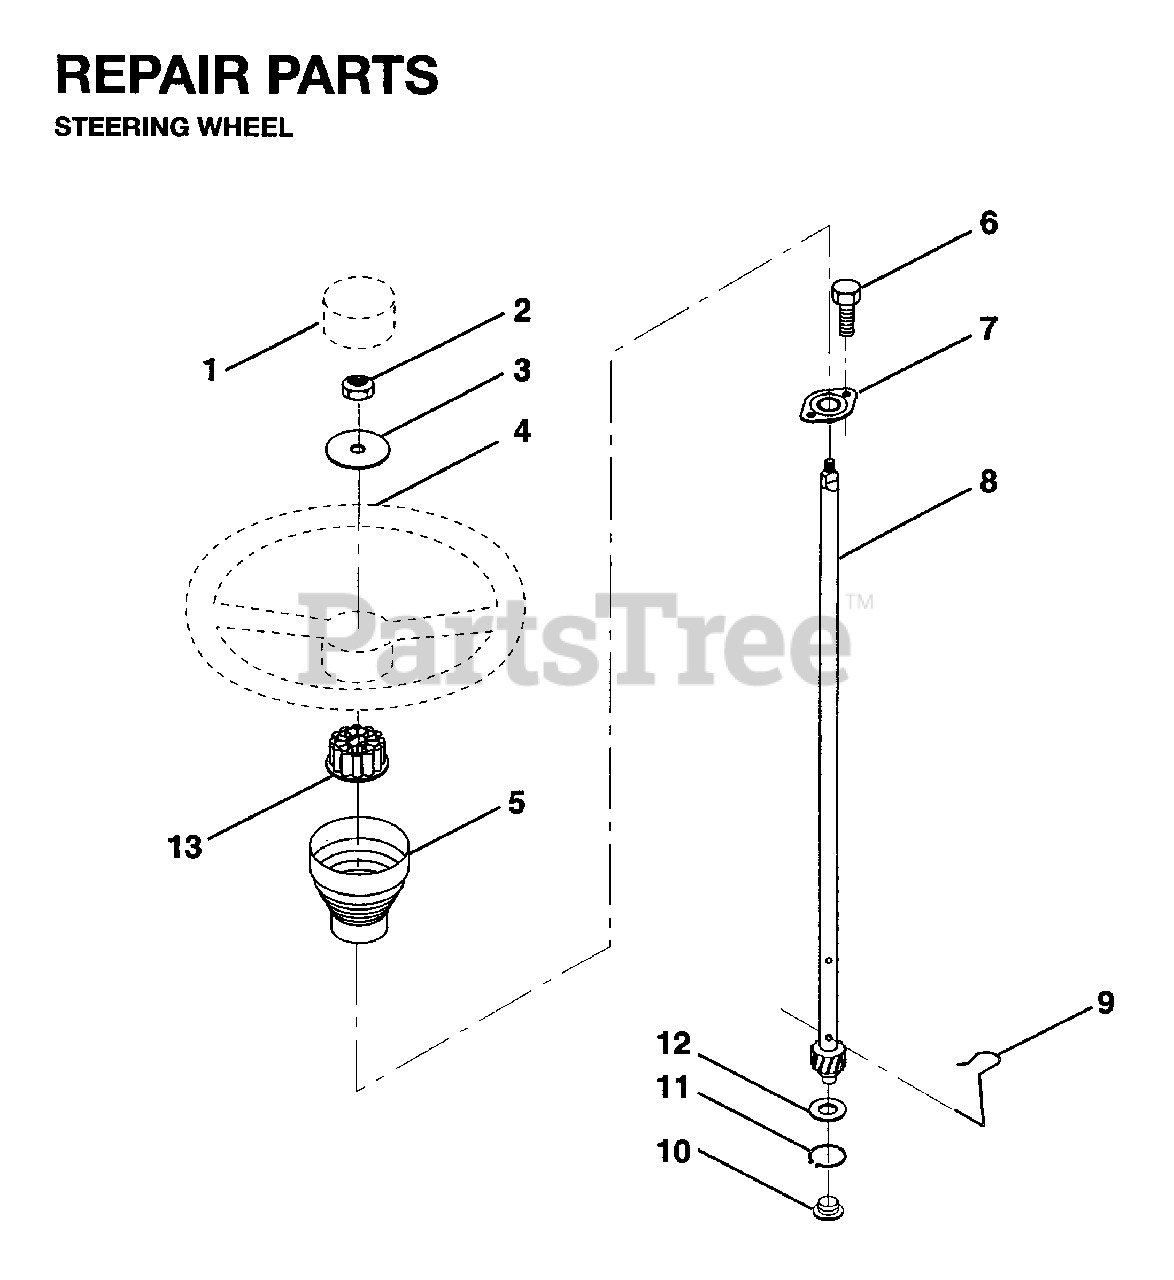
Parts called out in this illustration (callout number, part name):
2	NUT
3	WASHER T
7	BUSHING-STRG LT
8	SHAFT STEERING
9	STEERING CLIP
10	BUSHING STEER LWR
13	ADAPTER-WHEEL LT
